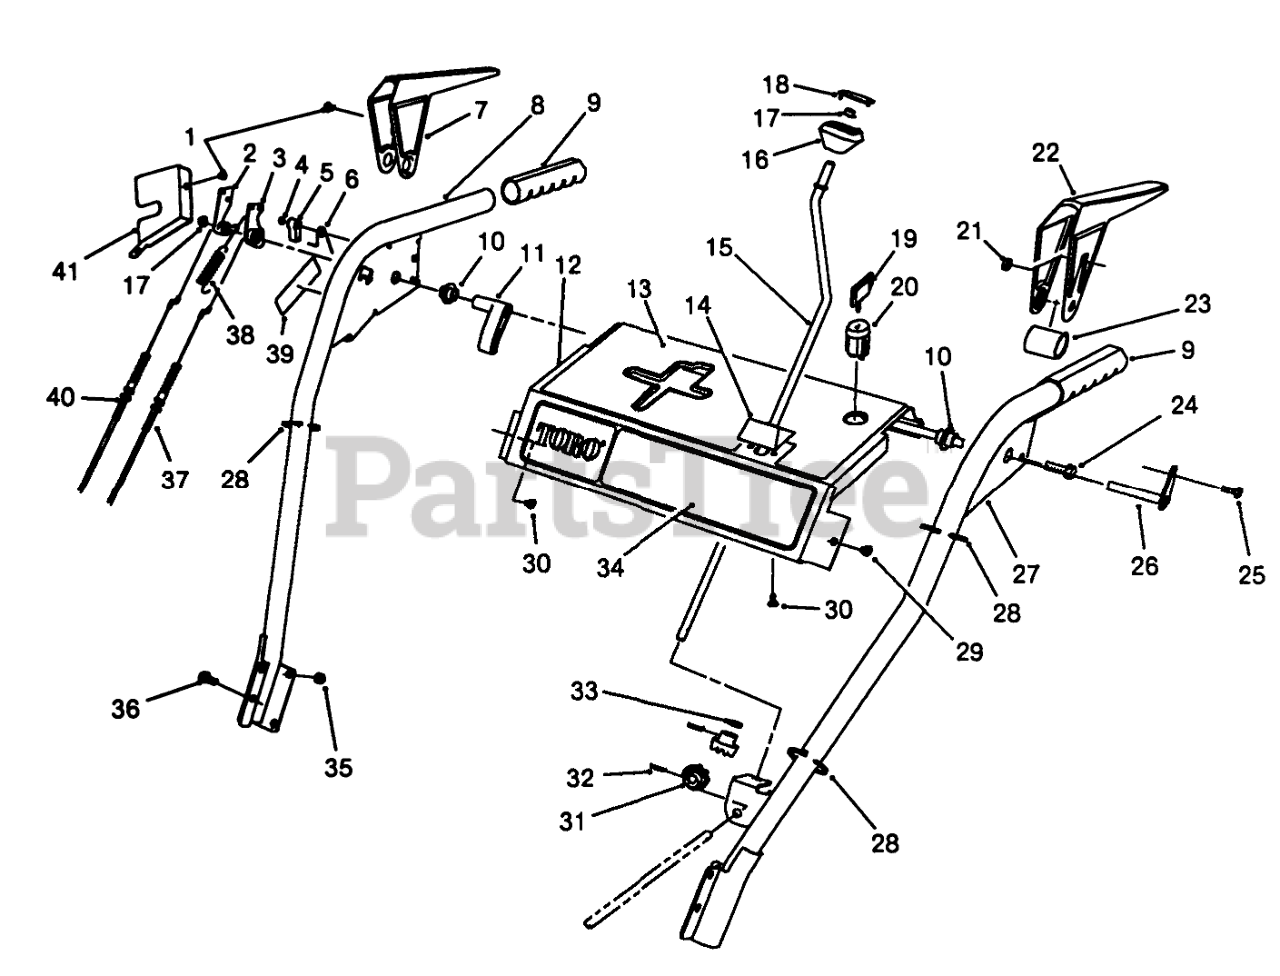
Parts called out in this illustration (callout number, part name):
1	SCREW-HH
2	TANG-LOCKING
3	CAM-RELEASE
4	E-RING-RETAINER
5	LATCH-LOCKING
6	SPRING-TORSION
7	Lever-Impeller
8	Handle-RH
9	HANDLE GRIP
10	BUSHING-LEVER
11	LEVER-TRIP
12	Panel-Control
13	Decal-Panel, Top
14	PLATE-GUIDE
15	CRANK-ROD, CHUTE
16	KNOB-CONTROL, CHUTE
17	RETAINER-PUSH ON
18	COVER-KNOB
19	KEY-IGNITION
20	SWITCH
21	NUT-LOCK, NI
22	Lever-Traction
23	SPACER-LEVER, TRACTION
24	SCREW-HHF
25	SCREW-HWH
26	CROSS ROD ASM
27	LH HANDLE WA (24")B
28	TIE-CABLE
29	SCREW-HWHTF
30	SCREW-PPH
31	GEAR-UNIVERSAL
32	PIN-SPRING
33	WASHER-RUBBER
34	DECAL-FRONT PANEL (824)
35	NUT-LOCK, NI
36	SCREW-HHF
37	CABLE-TRACTION
38	Spring-Extension
39	Decal-Warning
40	CABLE-IMPELLER
41	Cover Lever Lock
